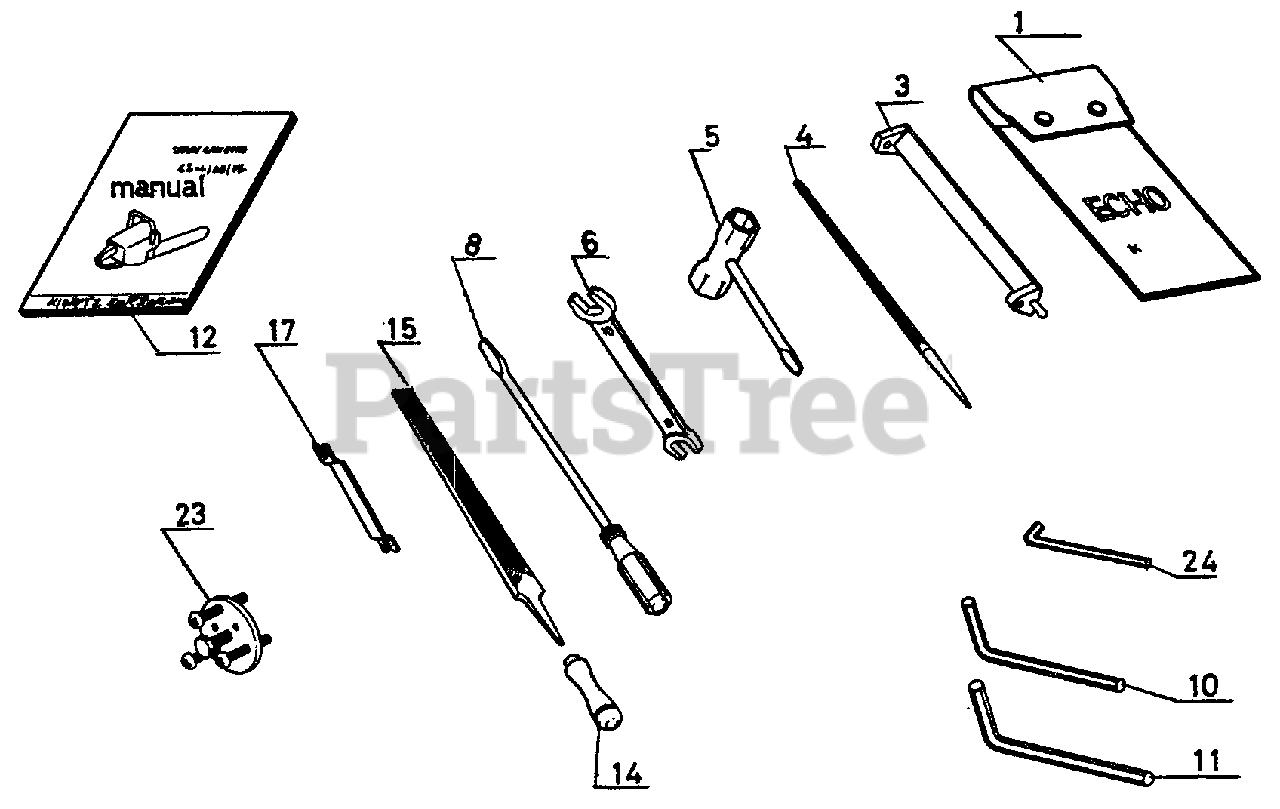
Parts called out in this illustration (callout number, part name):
1	BAG, TOOL
3	FILE HOLDER
4	ROUND FILE
5	WRENCH, T 17×19 MM
6	SPANNER - 8×10
8	SCREWDRIVER
10	WRENCH, ALLEN 4 MM
11	WRENCH, ALLEN 5 MM
12	OWNER'S MANUAL
14	FILE GRIP
15	FLAT FILE
17	GAUGE, DEPTH
23	PULLER
24	WRENCH, ALLEN 3 MM
